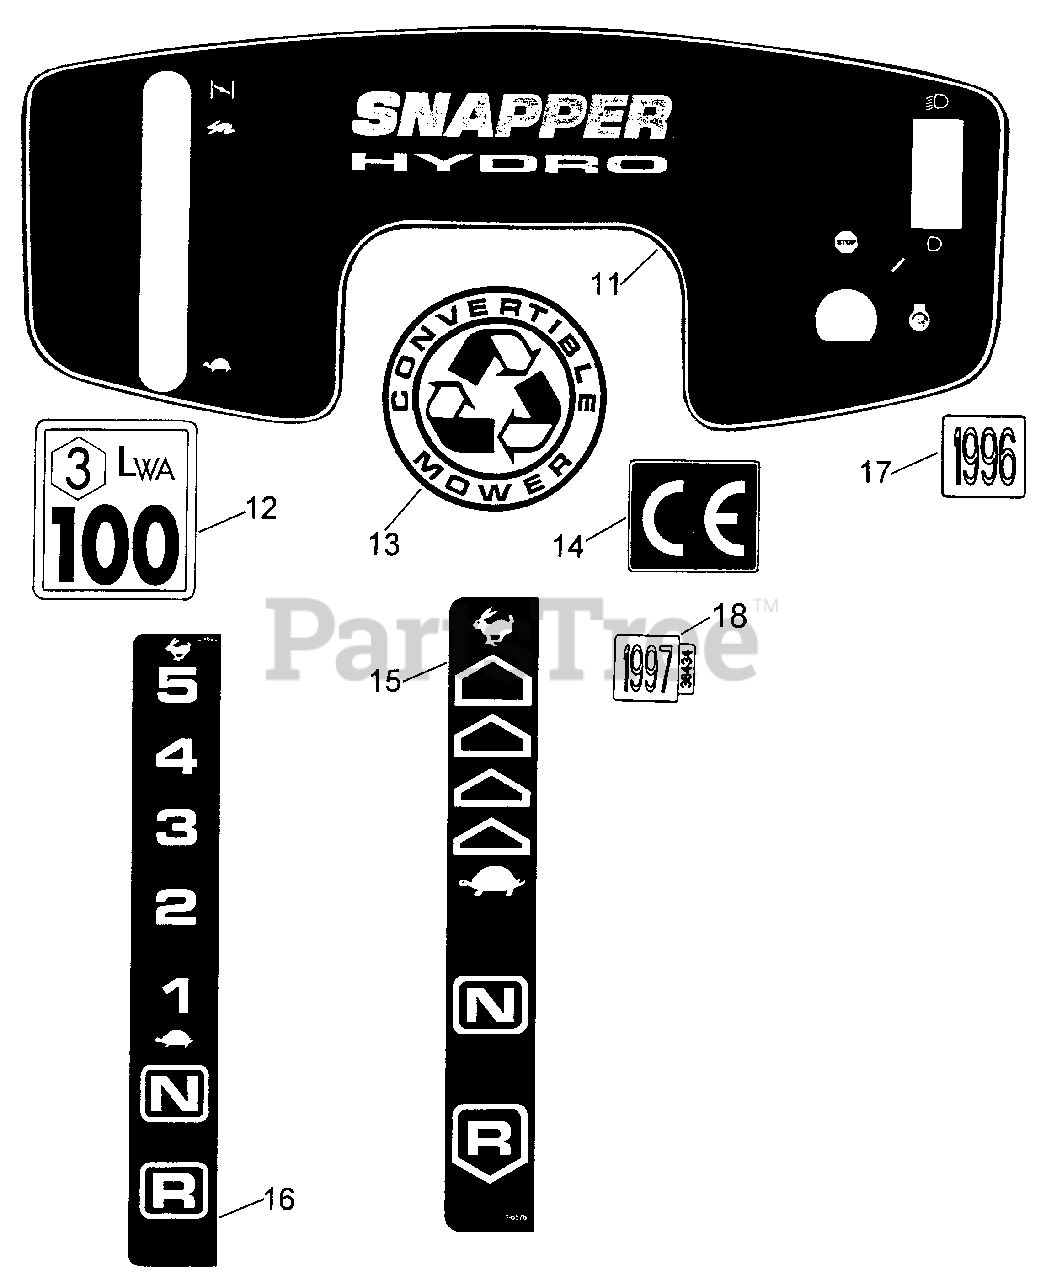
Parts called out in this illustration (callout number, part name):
11	DECAL, Console, Basic
11	DECAL, Console, No light
12	DECAL, Noise Control, Euro
13	LOGO, Convert - Blue/Silver
14	DECAL, European Community
15	DECAL, Shift Cover
16	DECAL, Shift Detent (5-Speed)
17	DECAL, 1996 Year of Manufacture
18	DECAL, 1997 Year of Manufacture
